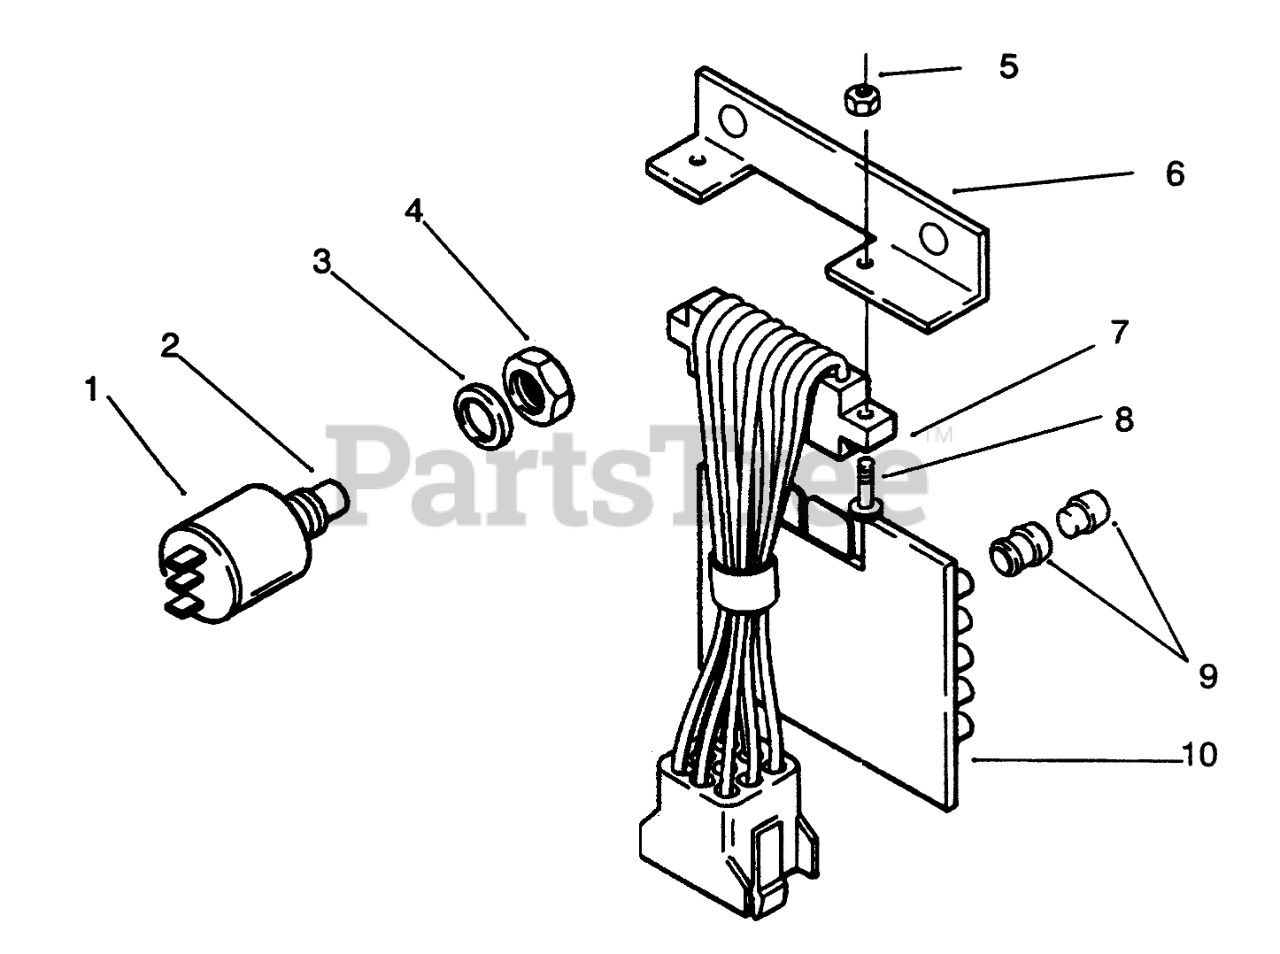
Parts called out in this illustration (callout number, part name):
1	Test Switch (Incl. Ref. #2-4)
2	BUTTON F/W 116796
3	Washer
4	NUT F/W 116796
5	NUT-HEX
6	BRACKET
7	P.C.-BOARD HARNESS
8	Screw
9	ASSY LENS & BUSHING
10	Board-Pc
